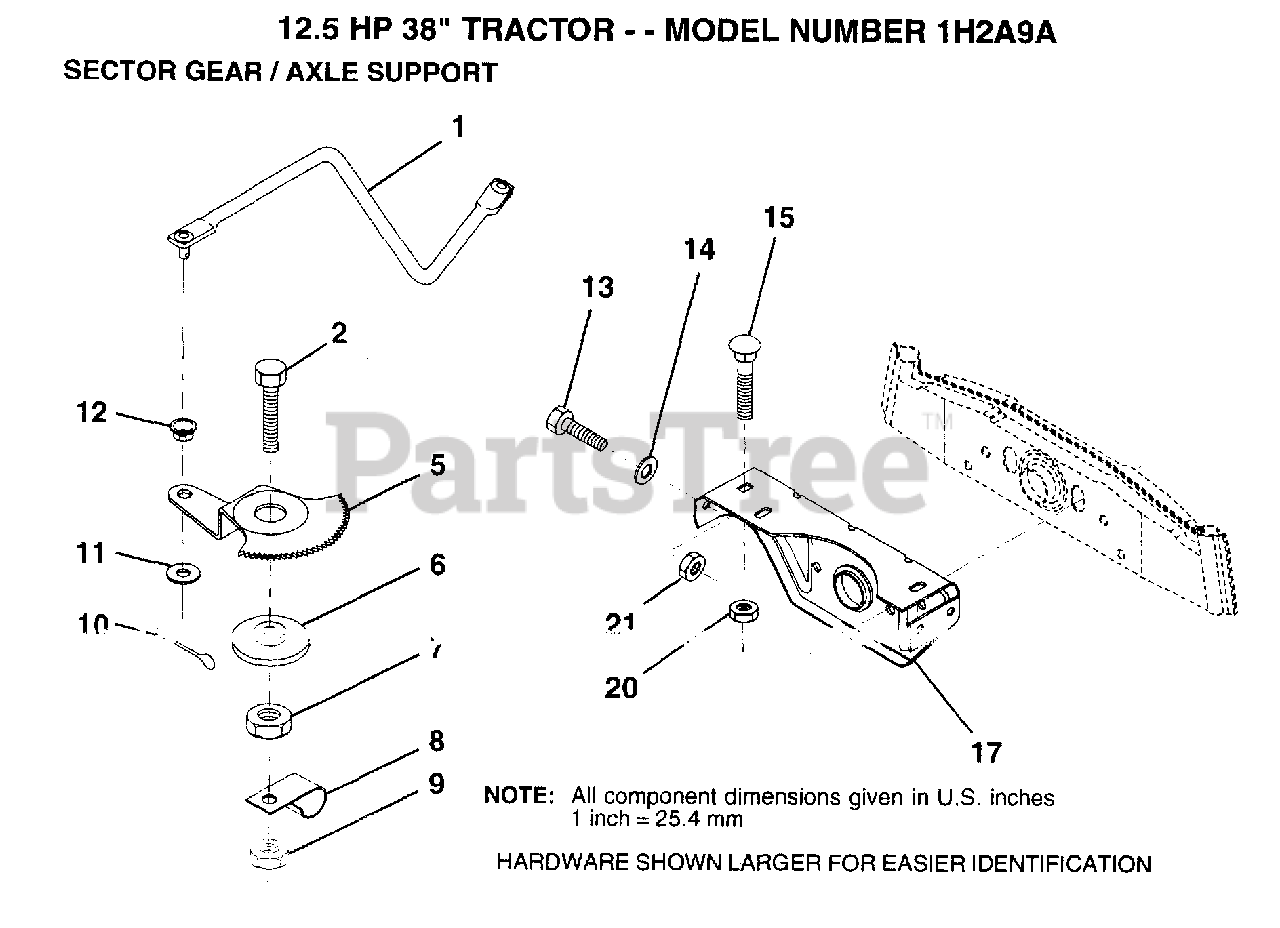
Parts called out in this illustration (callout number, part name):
1	DRAG LINK
2	"BOLT,HEX"
5	GEAR SECTOR
7	NUT
8	CLIP INSULATOR
9	NUT LTV
10	COTTER PIN
11	WASHER
12	BUSHING.DRAGLINK
13	BOLT
14	WASHER
15	BOLT
17	SUPT AXLE FRONT
